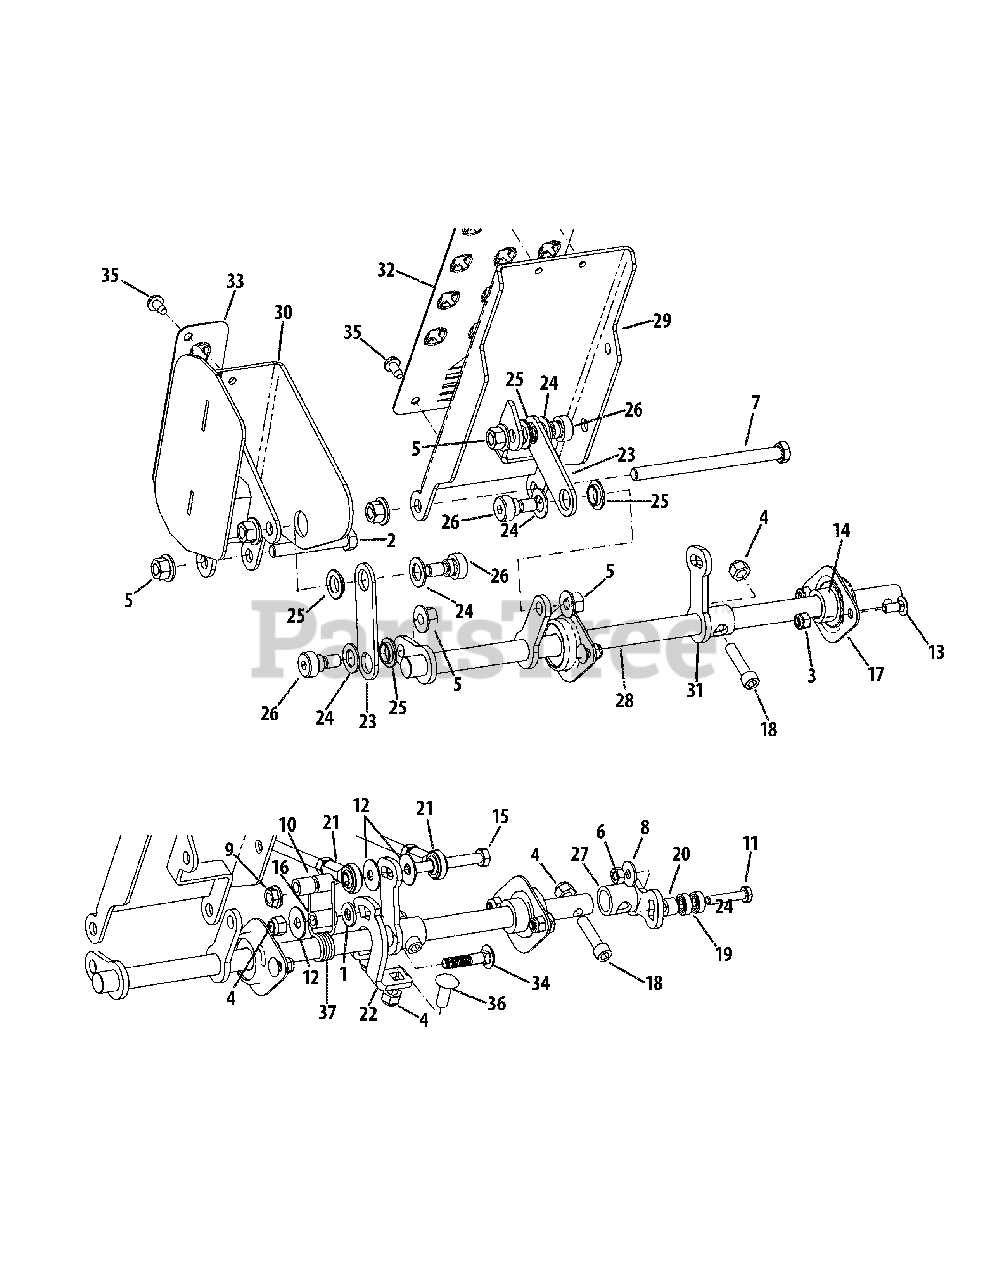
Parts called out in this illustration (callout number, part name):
1	Washer, .344 x .688 x .063
2	Hex Screw, 3/8-16 x 2.50
3	Nut, 1/4-20
4	Nut, 5/16-18
5	Flange Counter Lock Nut, 3/8-16
6	Counter Lock Nut, 1/4-20
7	Hex Screw, 3/8-16 x 5.00
8	Bell Washer, .265 x .75 x .062
9	Flange Counter Lock Nut, 5/16-18
10	Spacer, .315 x .500 x .520
11	Hex Screw, 1/4-20 x 1.25
12	Bell Washer, .325 x .930 x .045
13	Carriage Bolt, 1/4-20 x .620
14	Shaft Collar, .625 x 1.00 x .438
15	Hex Screw, 5/16-18 x 2.50
16	Spacer, .315 x .500 x .699
17	Flange Bearing
18	Screw, 5/16-18 x 1.25
19	Ball Bearing, .25 x .625 x .196
20	Spacer, .256 x .500 x .330
21	Speed Control Link Assembly
23	Pedal Control Link
24	Washer, .51 x .88 x .06
25	Flange Bearing, .502 x .875 x .180
26	Shoulder Bolt, 3/8-16 x .50 x .25
27	Lockout Hub Assembly
28	Pedal Bellcrank Assembly
29	Forward Pedal Assembly
30	Reverse Pedal Assembly
31	Control Arm Assembly
32	Forward Pedal Grip
33	Reverse Pedal Grip
34	Carriage Bolt, 5/16-18 x 1.50
35	Screw, 1/4-20 x .5
36	Carriage Bolt, 5/16-18 x .875
37	Torsion Spring, .66 x .56
